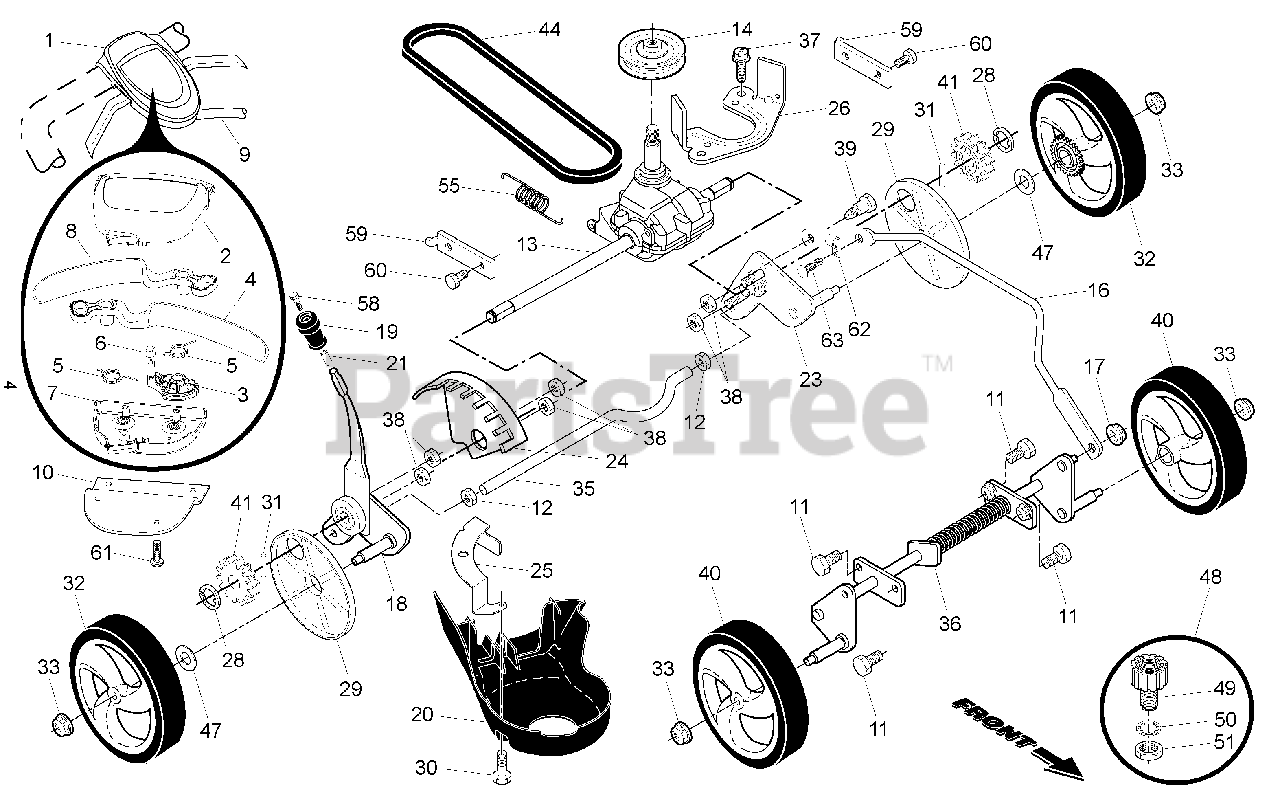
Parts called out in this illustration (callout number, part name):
1	Drive Control Assembly
2	Cover, Top
4	Lever, Drive Control, LH
5	Spring, Return
7	Cover, Bottom
8	Lever, Drive Control, RH
9	Cable, Drive
10	Mounting Bracket, Drive Control
13	Gear Case Assembly, Complete
14	Pulley, Drive
16	Rod, Connecting
17	Nut, Hex
18	Kit, Selector Assembly
19	Knob, Wheel Adjuster
20	Debris Shield
23	Wheel Axle Assembly, LH
24	Bracket, Height Adjustment
25	Mounting Bracket, Debris Shield
26	Belt Keeper
28	E-Ring 7/16
29	Cover, Dust, Wheel
31	Pawl, Drive
32	Wheel & Tire Assembly, Rear
33	Nut, Flangelock 3/8-16
35	Axle, Rear
36	Axle, Front
37	Screw, Hi-Lo Thread, 12 x 5/8
40	Wheel & Tire Assembly, Front
44	Belt, Drive
47	Washer, Flat
48	Kit, Water Washout Assembly
49	Fitting, Water Washout
50	Washer, Lock, Internal Tooth
51	Locknut, Hex, with O-Ring
55	Spring, Tension
58	Bolt, Shoulder
59	Support Bracket
60	Bolt, Hex Head
62	Clip, Cable
63	Fastener, Push
